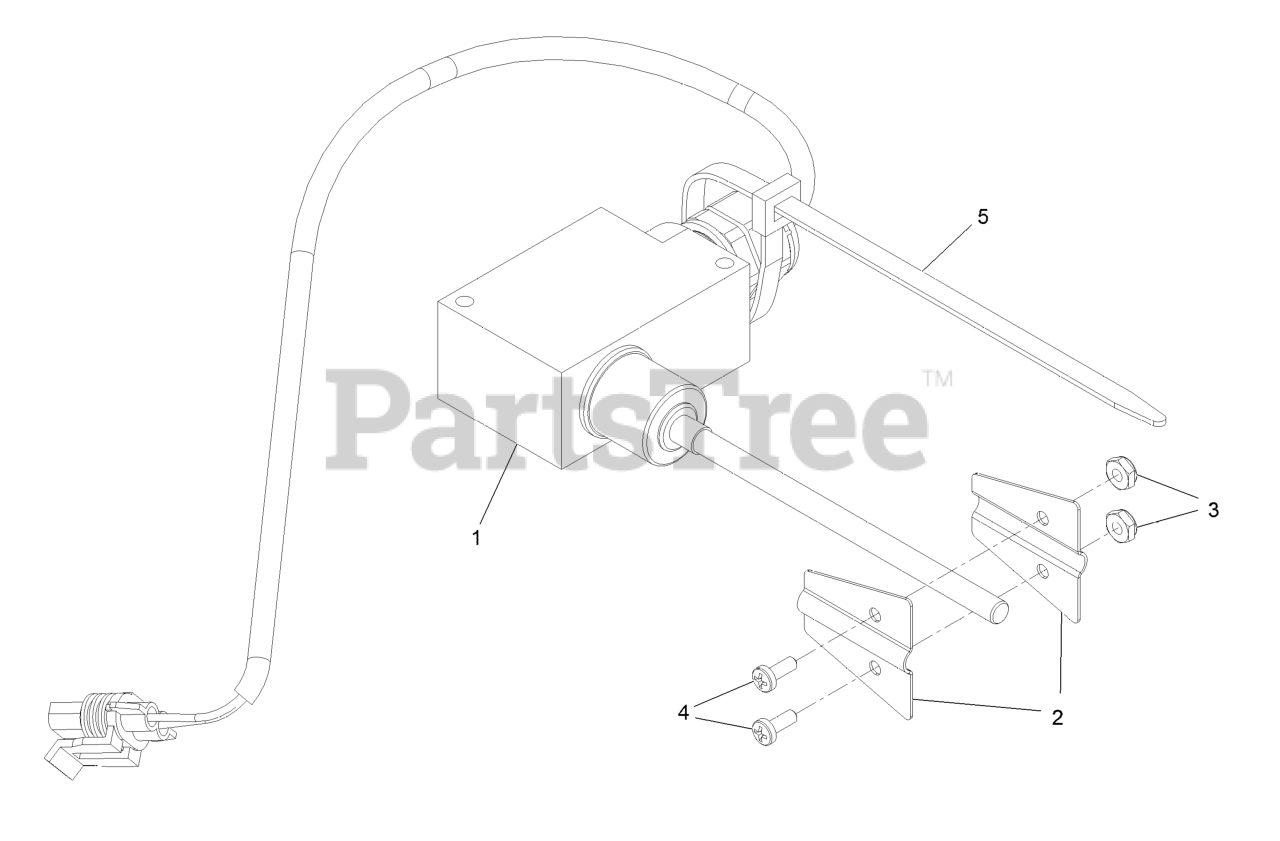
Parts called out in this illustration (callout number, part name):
1	FILL SENSOR WIRE KIT
2	FLAG- SENSOR, FILL
3	NUT-HEX
4	SCREW-PAN
5	TIE-PLASTIC
